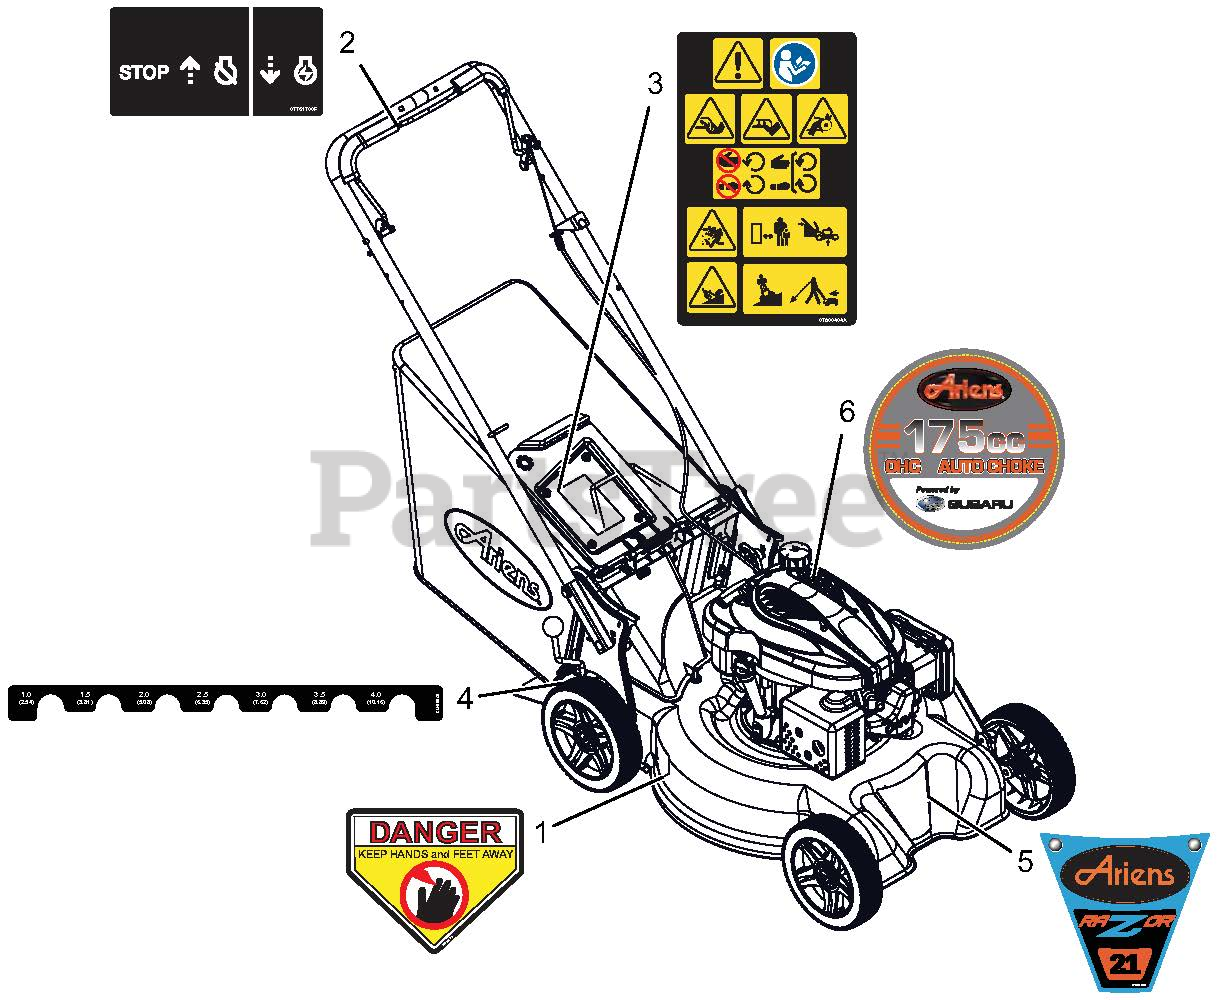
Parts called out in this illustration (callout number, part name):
1	DECAL, DANGER
2	DECAL - ENGINE CONTROL
3	DECAL,MAIN SAFETY_WAW LM
4	DECAL, HOC
5	DECAL, ARIENS RAZOR STYLE
6	DECAL, ENGINE STYLE, ARIENS CE
